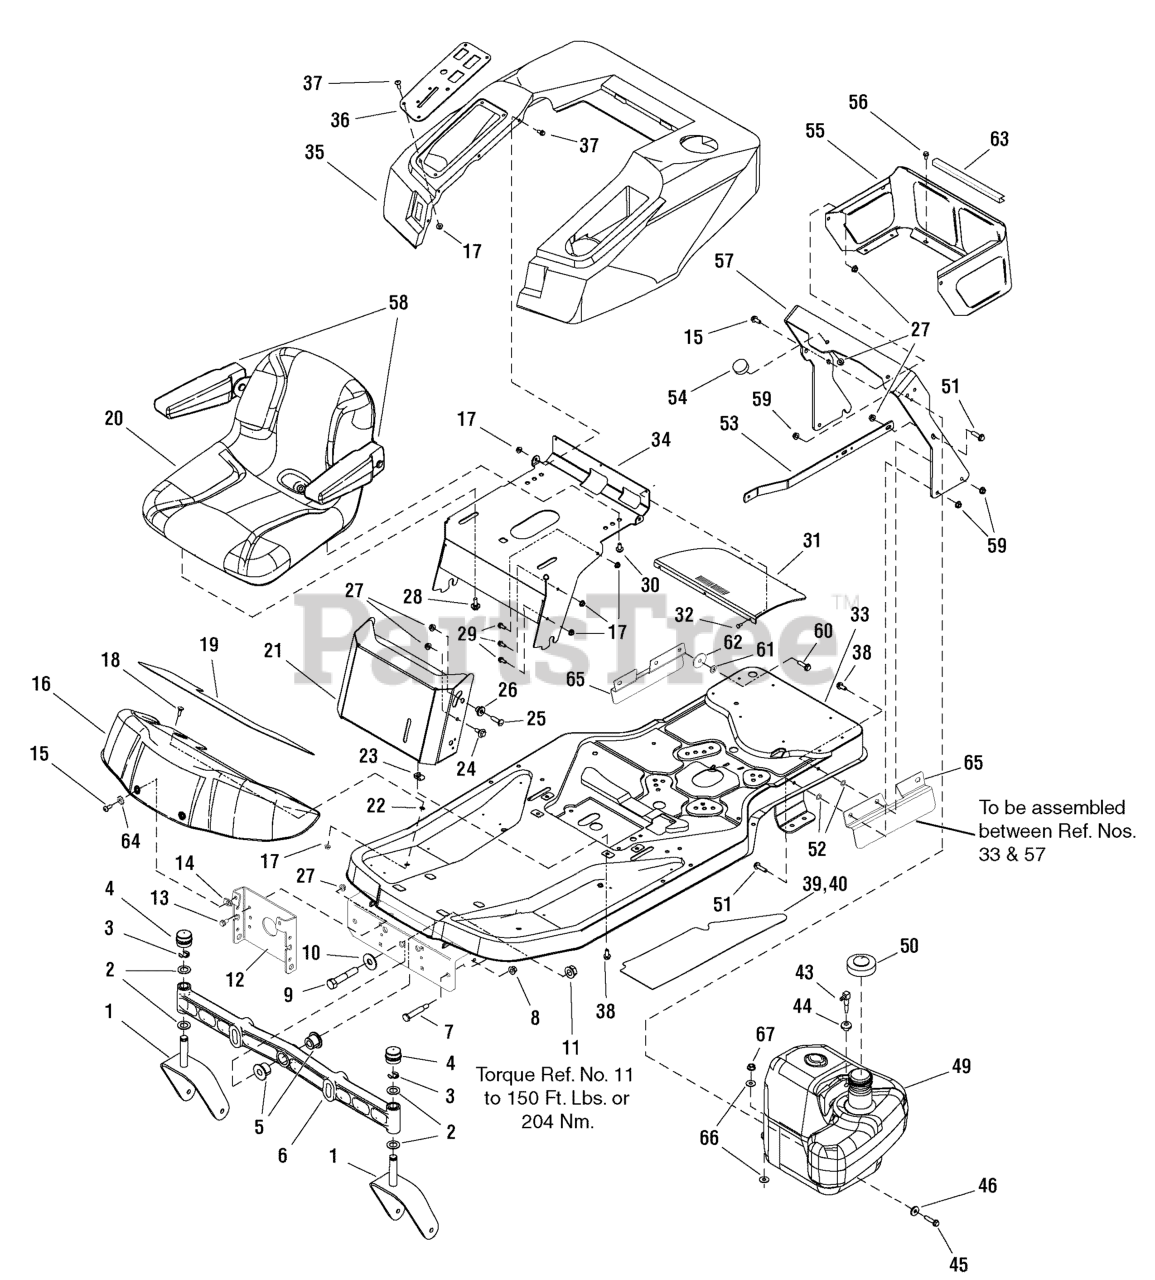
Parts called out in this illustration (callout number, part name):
1	CASTER ASSEMBLY
2	WASHER, 3/4 ID x 1.6 OD x .05 THK
3	RING, Klipring, 3/4
4	CAP, Hub
5	BUSHING, Axle Pivot
6	AXLE, Casting
7	BOLT, Shoulder, G5
8	NUT, Hex Flange, 3/8-16 ESNA
9	CAPSCREW, Hex Head, 5/8-11 x 3 1/4
10	WASHER, 5/8, .64 ID x 1-3/4 OD x .11 THK
11	NUT, Hex Flange Two-Way Lock, 5/8-11
12	BRACKET, Front Footrest Support
13	SCREW, Hex Head Taptite, 5/16-18 x 5/8
14	NUT, Speed Lug Type, 1/4-20
15	CAPSCREW, Hex Head, 5/16-18 x 1
16	FRONT FOOTREST Sears 6000 Craftsman Red
17	NUT, Hex Flange, 1/4-20 ESNA
18	CARRIAGE BOLT, 1/4-20 x 3/4, G5
19	PAD, Footrest Panel
20	SEAT ASSEMBLY, with Armrests
21	PANEL, Front - Manual Brake and Deck Lift
22	NUT, Push, 1/4
23	NUT, Speed, Lug Type, 5/16-18
24	BOLT, Shoulder
25	BOLT, Carriage, 5/16-18 x 1 1/4
26	PIVOT, Hood, Powdered Metal
27	NUT, Hex Flange Whiz Lock, 5/16-18
28	BOLT, Shoulder, G5
29	SCREW, Hex Whiz Lock Flange, 1/4-20 x 5/8
30	SCREW, Hex Flange Whiz Lock, 5/16-18 x 3/4 Dog PT
31	SCREEN, Seat Deck
32	RIVET, Pop
33	FRAME ASSEMBLY
34	SUPPORT, Seat
35	SEAT DECK, Plastic Sears Craftsman Red ZTS
36	PLATE, Control
37	SCREW, Truss Head Torx, 1/4-20 x 3/4
38	SCREW, Hex Whiz Lock Flange, 5/16-18 x 3/4
39	PAD, Footrest R.H.
40	PAD, Footrest L.H.
43	ELBOW, Gas Tank
44	BUSHING, Fuel
45	CAPSCREW, 5/16, 18 x 1-1/2
46	WASHER, 5/16, .34 ID x 1 OD x .13 THK
47	LOCKWASHER, External Tooth, 3/8
49	TANK, Fuel
50	CAP, Fuel Tank
51	CAPSCREW, Hex Head, 5/16-18 x 1 1/4
52	NUT, Push Pal, 5/16 DIA Thread, 5/8 OD
53	BRACE, Tank
54	BUMPER, Rubber
55	SHROUD, Rear
56	SCREW, Hex Washer Head Taptite, 1/4-20 x 1/2
57	SUPPORT, Seat Deck
58	ARM REST KIT, L.H. & R.H.
59	NUT, Hex Flange Nylock, 5/16-18
60	CAPSCREW, 3/8 - 16 x 1-1/4
61	NUT, Push Pal, 3/8
62	WASHER, 3/8
63	TRIM, 8"
64	WASHER, External Tooth, 1/4
65	GUARD, Debris
